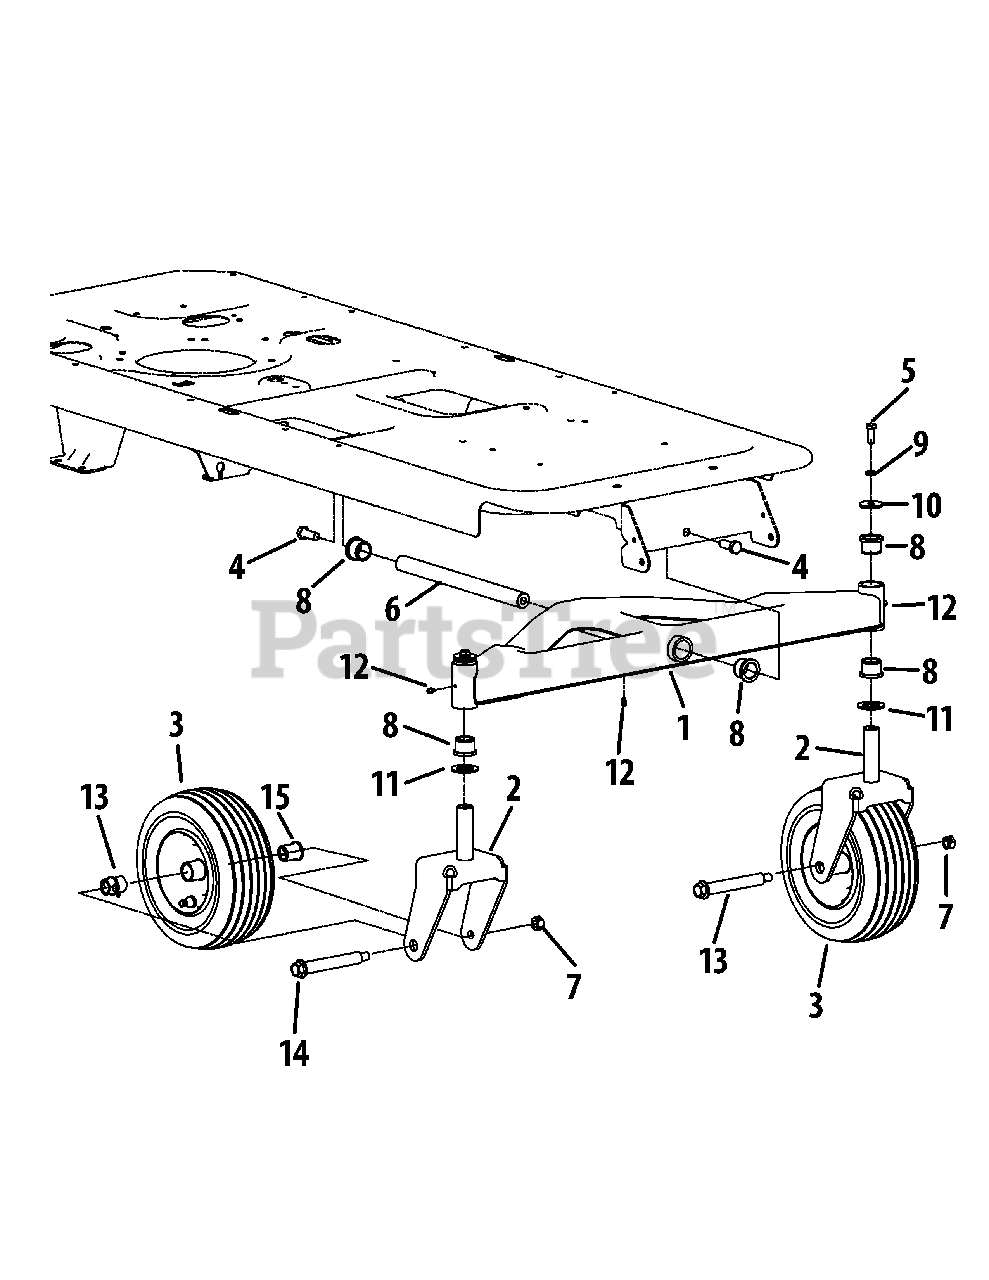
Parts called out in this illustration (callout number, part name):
1	Front Pivot Axle
2	Castor Wheel Bracket
3	Wheel Assembly, 11.0 x 4.0 x 5.0
4	Hex Lock Screw, 1/2-13 x 1.25
5	Hex Cap Screw, 3/8-16 x 1.0
6	Axle Shaft
7	Hex Lock Nut, 1/2-13
8	Flange Bearing, 1.0 x 1.246
9	Lock Washer, 3/8
10	Flat Washer, .39 x 1.5 x .134
11	Flat Washer, 1.0 x 1.75 x .107
12	Lube Fitting, 3/16 Drive
13	Shoulder Screw, .75 x 4.75 x 7/16-14
14	Flange Bearing, .76 x 1.0 x 1.2
15	Flange Bearing, .76 ID w/ Lube Ftg.
